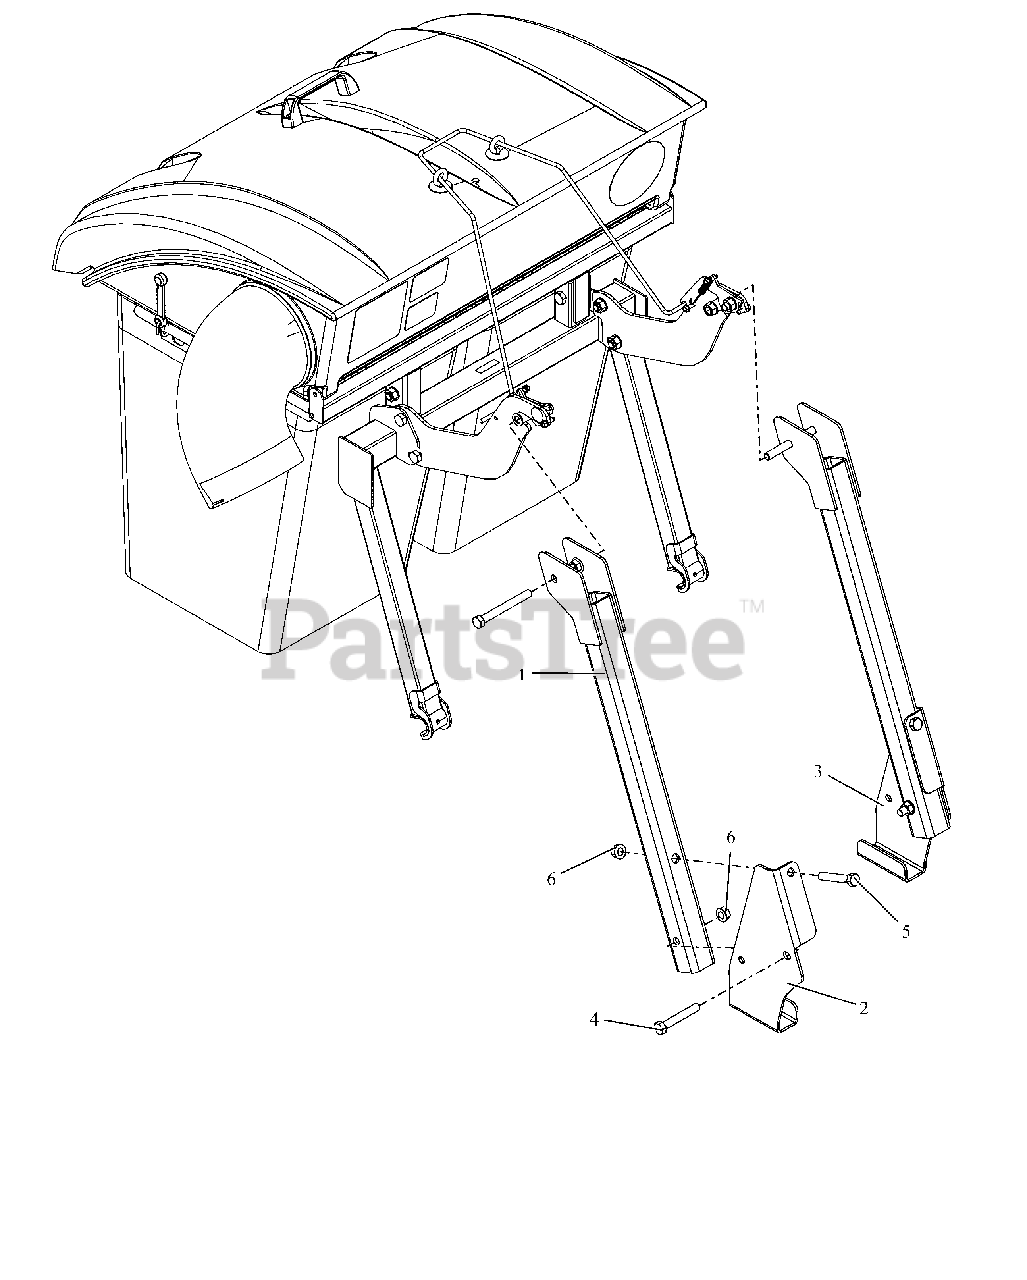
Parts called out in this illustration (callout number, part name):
1	WLDMT, BAGGER FRONT MOUNT
2	BRKT, ROPS SUPPORT - RH
3	BRKT, ROPS SUPPORT -LH
4	BLT,HEX .50-13X3.25 G5 ZCC
5	BLT, HEX .50-13X3.00 G5 ZCC
6	NUT-LK-TOP-FLG .500-13 GF ZCC
